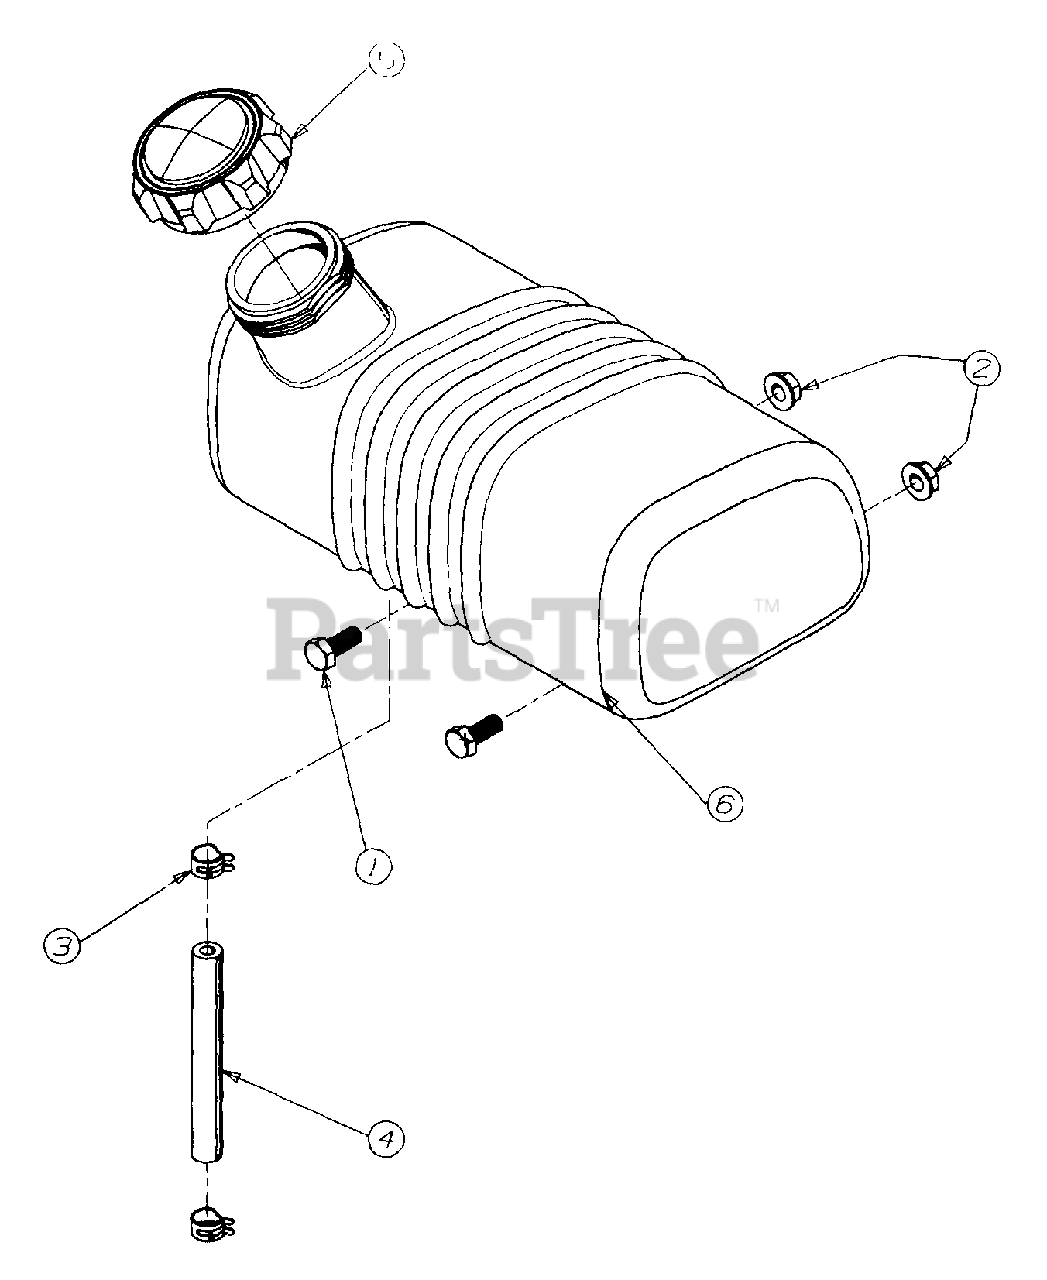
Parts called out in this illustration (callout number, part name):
1	SCREW-HEX
2	NUT-HEX LOCK FLANGE
3	CLAMP-HOSE
4	HOSE-FUEL LINE 8"
5	CAP-FUEL
6	TANK-FUEL 1 GALLON
